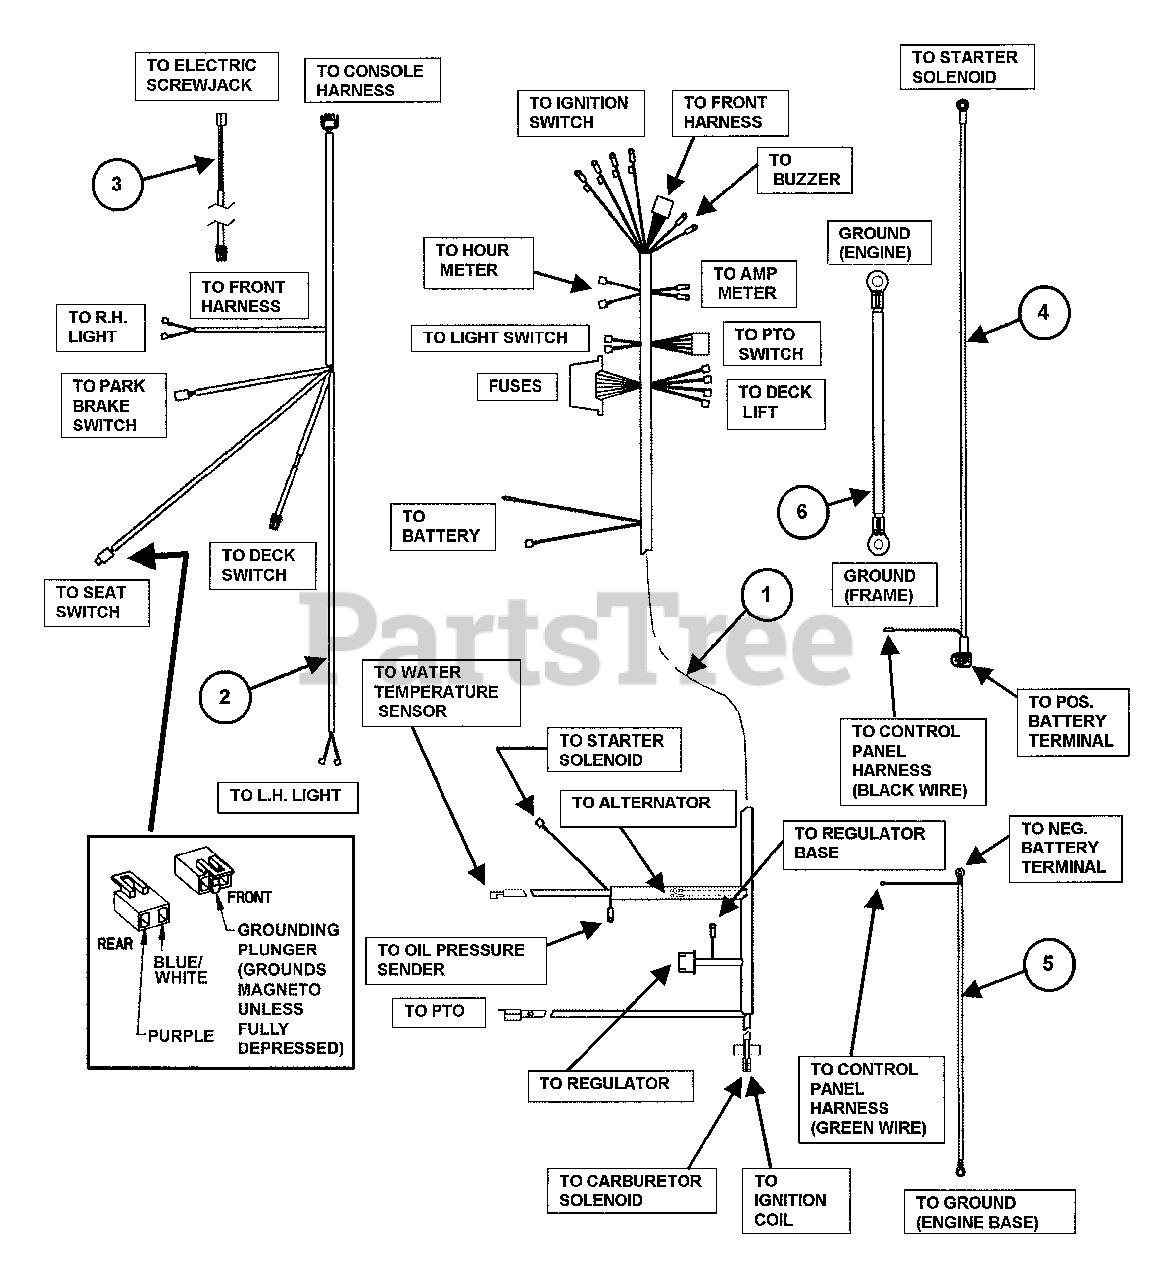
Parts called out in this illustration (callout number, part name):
1	HARNESS, Control Panel
2	HARNESS, Front
3	HARNESS, Deck Lift (15" Long)
4	CABLE, Battery-Positive (51" Long)
5	CABLE, Battery-Ground (38" Long)
6	CABLE, Chassis-Ground (18" Long)
